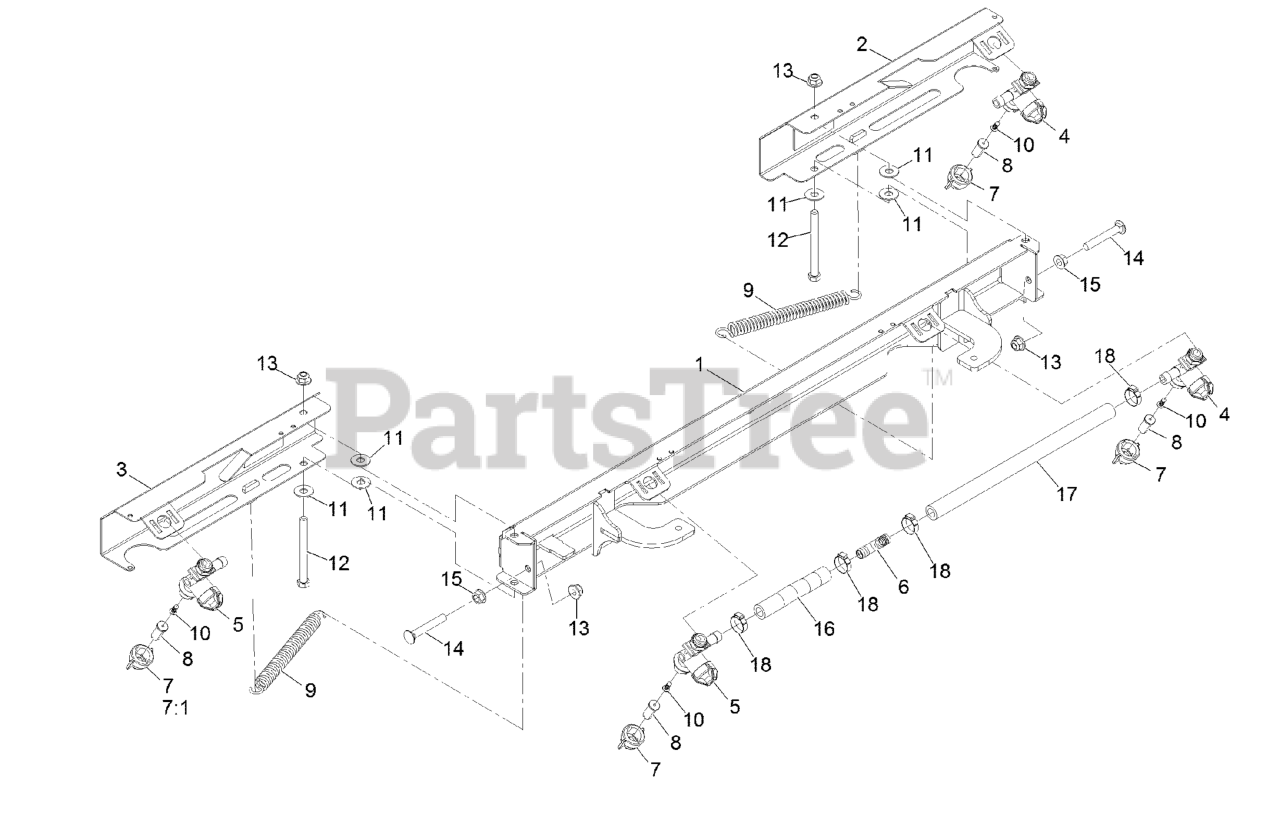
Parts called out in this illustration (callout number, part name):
1	Boom-Center
2	Boom-Wing, Rt
3	Boom-Wing, Lt
4	BODY-NOZZLE, RIGHT
5	BODY-NOZZLE, LEFT
6	FITTING-TEE, BARB
7	CAP-NOZZLE
7:1	SEAT-GASKET
8	TIP-SPRAY
9	SPRING-EXTENSION
10	STRAINER-NOZZLE, 50M 5PSI
11	WASHER-FLAT
12	SCREW-HH
13	Nut-Hex Flange
14	SCREW-CARR
15	Nut-Hex Flange
16	Hose-Spray
17	Hose-Spray
18	CLAMP-OETIKER, 167
